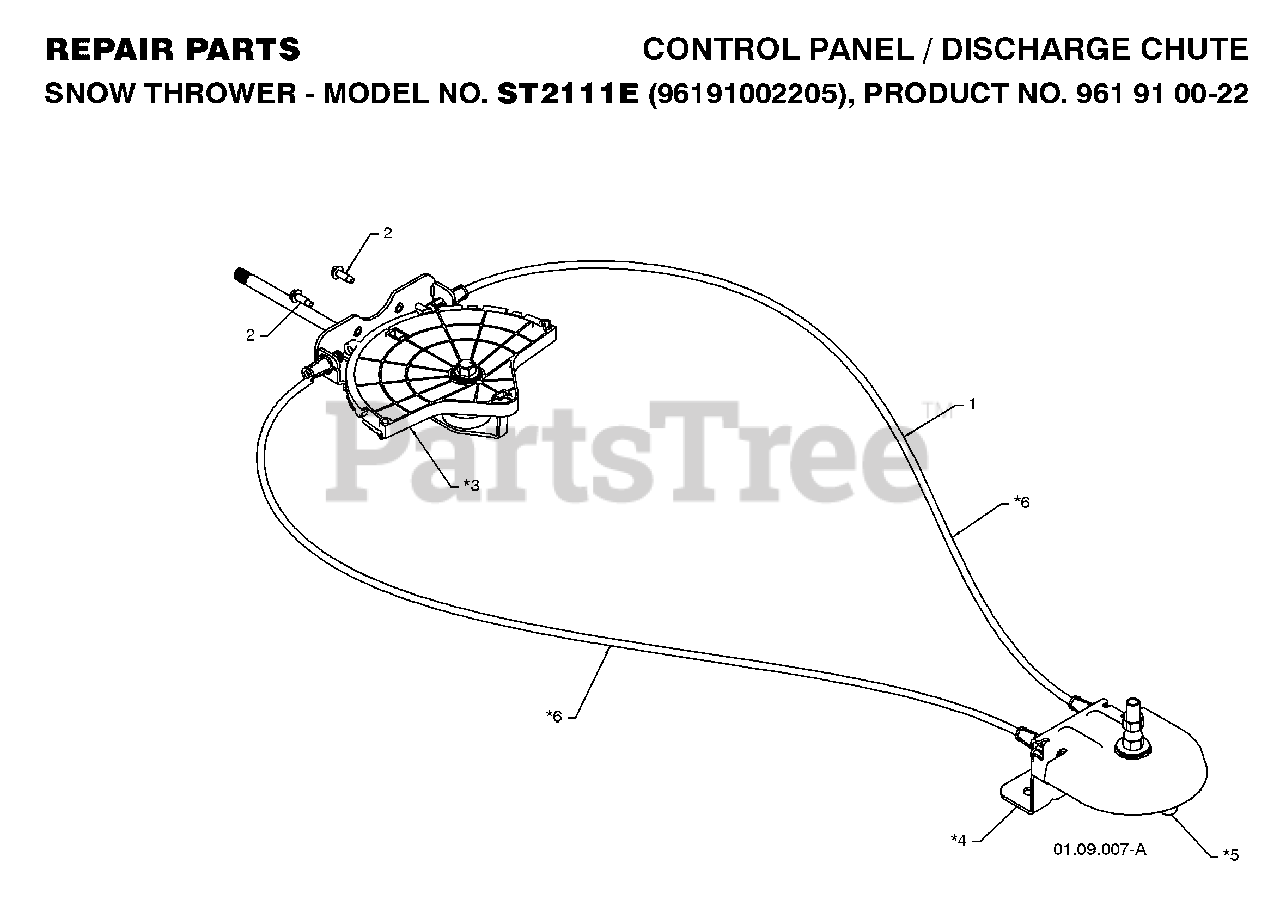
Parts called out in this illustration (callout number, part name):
1	LEVER/CABLE.ASM.ROTATOR
2	SCREW #10-24 X 5/8
3	CHUTE.ROT.HEAD.SERVICE
4	PIVOT.BRACKET
5	SNOW.PIVOT.PULLY
6	CABLE.ASSEMBLY
